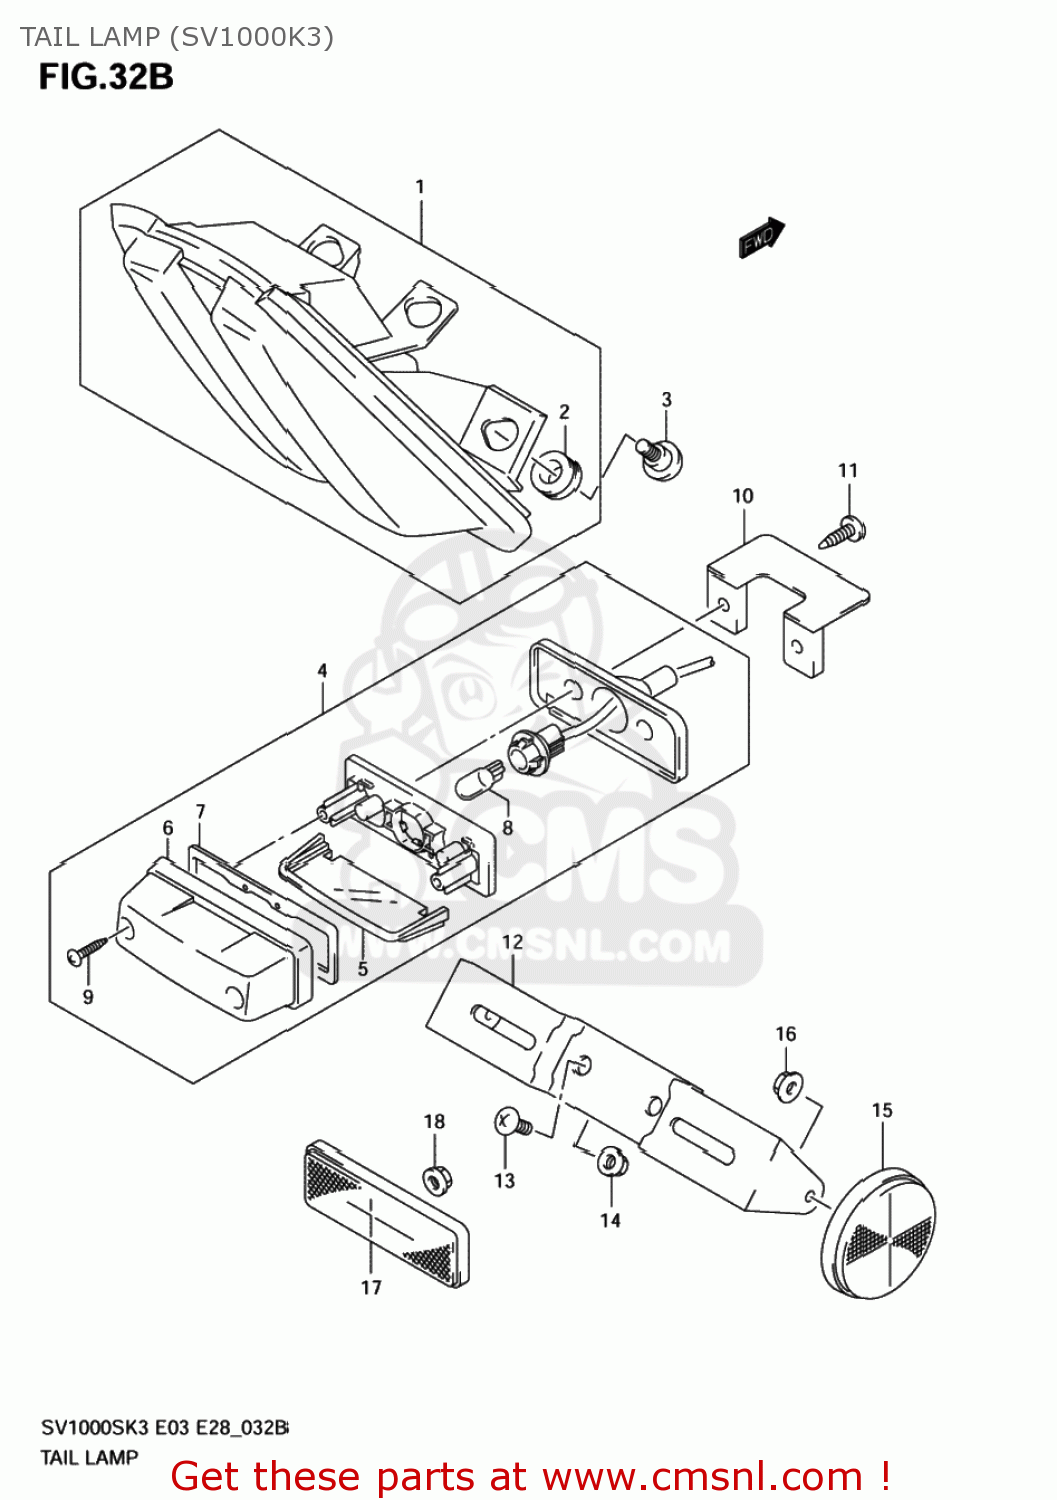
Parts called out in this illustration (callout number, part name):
1	LAMP ASSY,RR COMBINATION
2	CUSHION
3	SCREW(6X22.5)
4	LAMP ASSY,LICENSE
5	LENS
6	COVER
7	GASKET (NAS)
8	BULB(12V5W)
9	SCREW
10	BRACKET,LICENSE
11	SCREW
12	BRACKET,LICENSE PLATE
13	SCREW
14	NUT
15	REFLECTOR ASSY,RR SIDE
16	NUT
17	REFLECTOR ASSEMBLY,REAR
18	NUT
